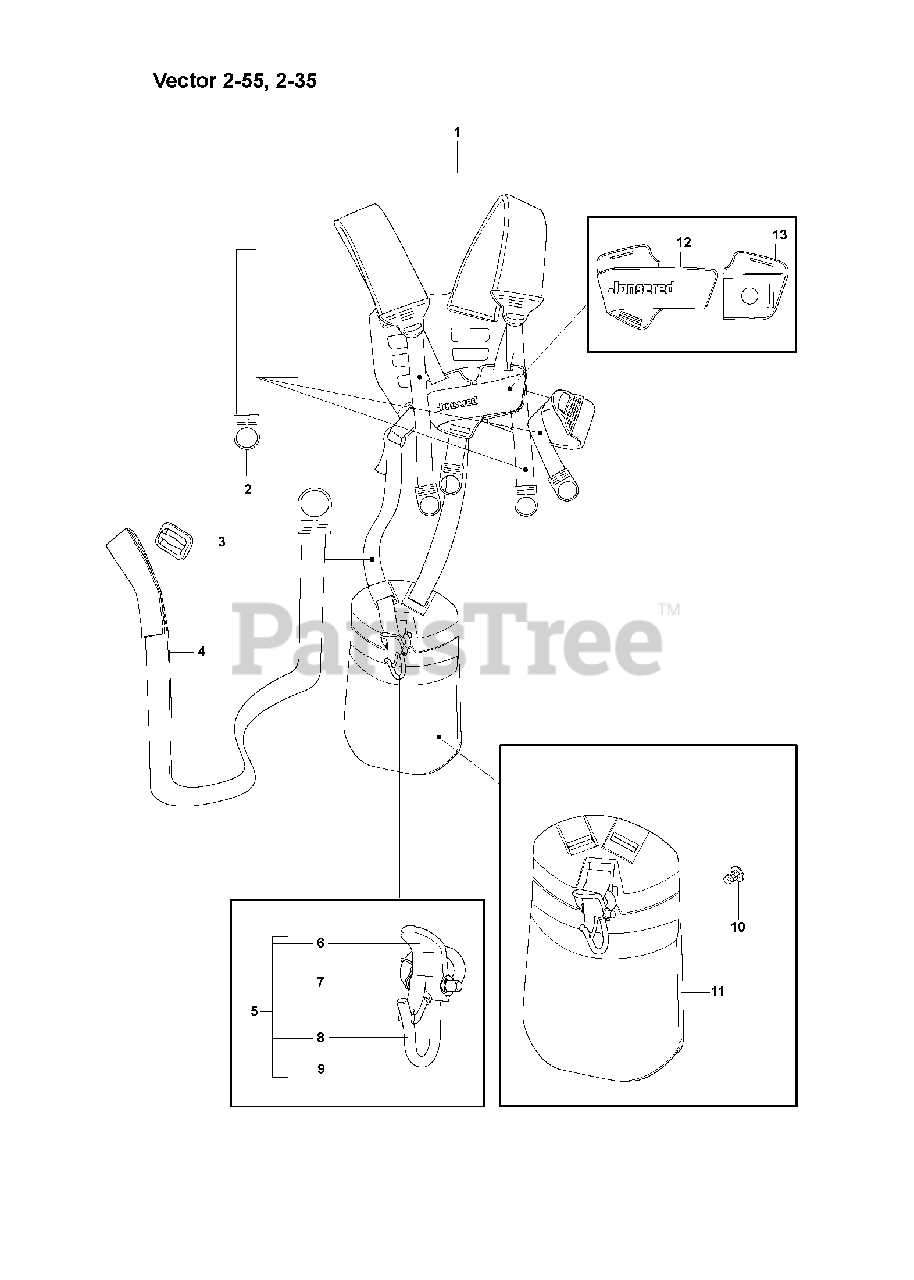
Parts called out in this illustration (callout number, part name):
1	HARNESS "VECTOR" 2-55
1	HARNESS COMPLETE
2	BAND
3	CLIP
4	BAND
5	HARNESS HOOK, COMPLETE
6	CATCH *
7	SPRING
8	HOOK
9	E-RING 5
10	RIVET
11	PROTECTOR
12	FRONT PIECE
13	FRONT PIECE
